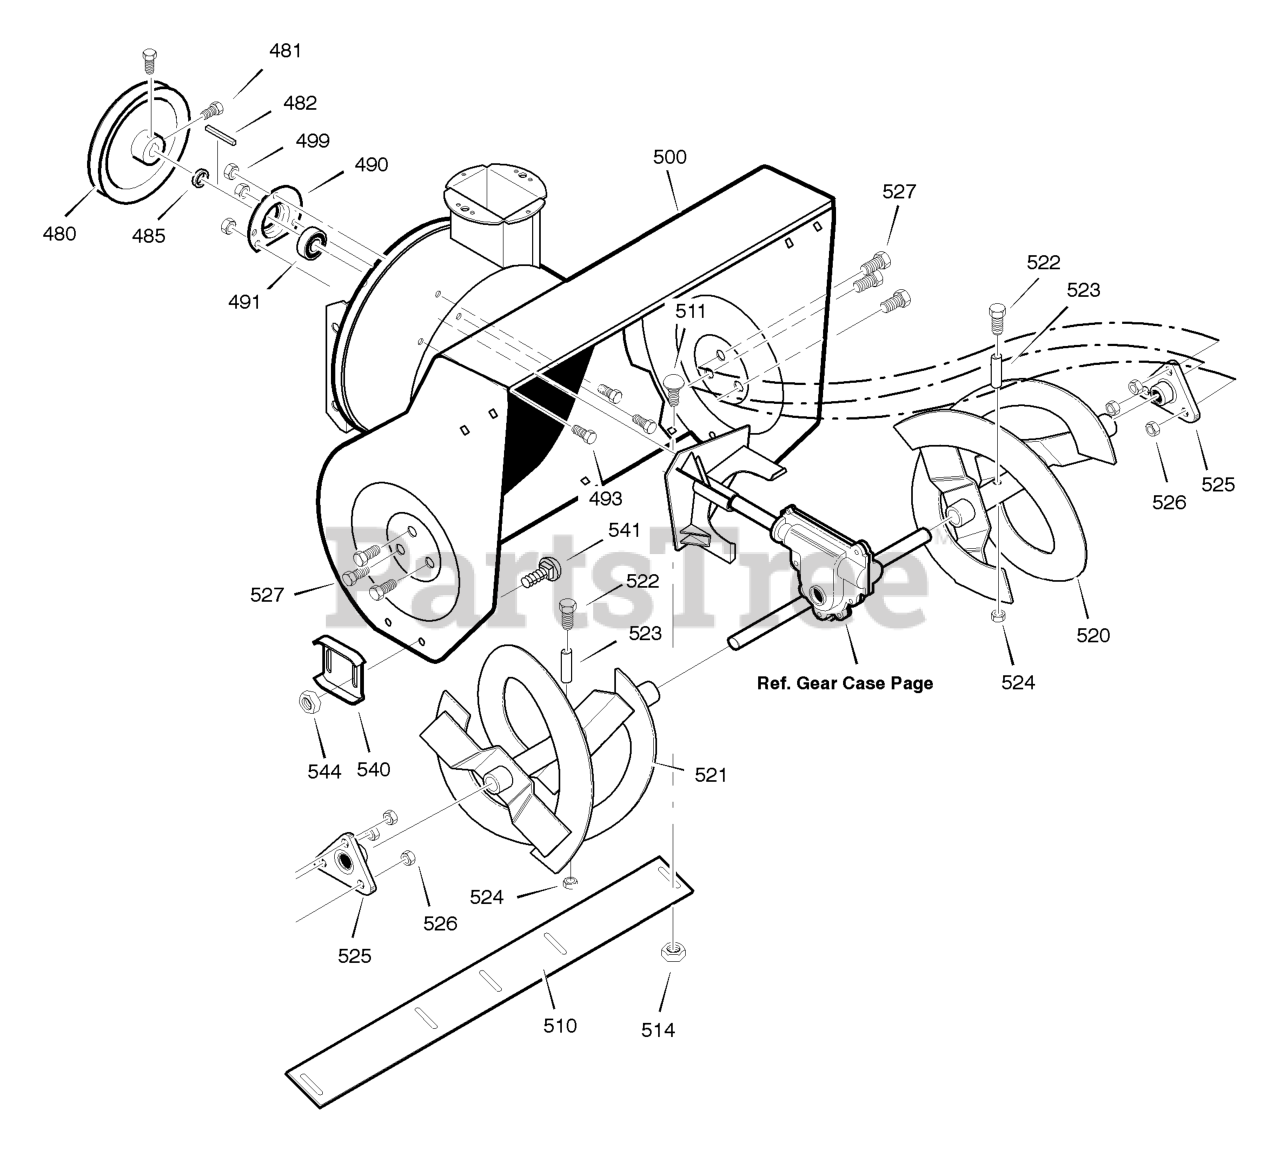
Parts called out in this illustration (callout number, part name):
480	PULLEY, 4L
481	SCREW, 5/16-18 x 0.63
482	KEY, SQUARE 3/16 X 3/4
485	SPACER, FRICTION PULLEY
490	RETAINER, BALL BRNG
491	BEARING, BALL
493	BOLT, HEX 5/16-18X .50
499	NUT, 5/16-18 HEXWDFLLK
500	HOUSING, ASSY
510	BLADE, SCRAPER
511	BOLT, 5/16-18 x 0.50
514	NUT, 1/4-20 x 0.75
520	AUGER, ASSY, LH
521	AUGER, ASSY, RH
522	SCREW, 1/4-20X1.75
523	SPACER, SLEEVE
524	NUT, 1/4-20
525	BEARING,FLANGE
526	NUT, 5/16-18
527	SCREW, 5/16-18 x 0.75
540	SKID, HEIGHT ADJUST
541	BOLT, 5/16-18 x 0.75
544	NUT, 5/16-18
